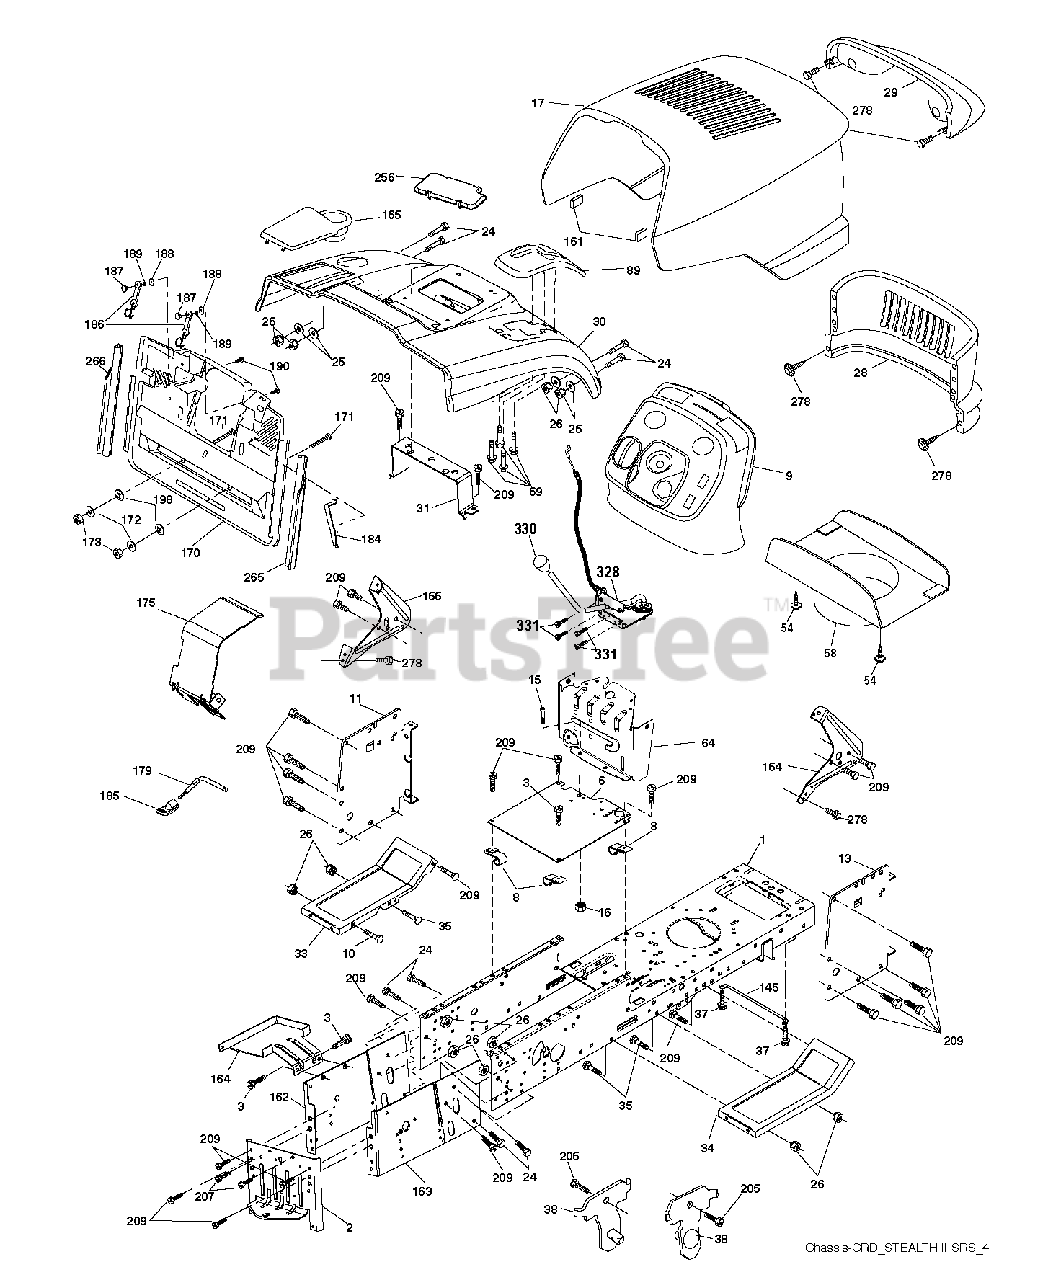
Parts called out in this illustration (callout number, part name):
1	CHASSIS
3	SCREW 3/8-16X3/4
8	CLIP,INSULATOR
10	BOLT D
13	PANEL DASH RH
16	NUT
25	WASHER
26	NUT
31	BRACKET SUPPORT FENDER
54	SCREW.WSHD.HEX10-32X5/8
58	DUCT HOOD
69	SCREW.HI-LO.CONSOLE
145	ROD.PIVOT.HOOD
161	EXTRUSION BUMPER
164	SUPPORT
171	BOLT
172	WASHER
186	LATCH ASSY
187	WELDNUT
189	LOCKWASHER
207	SCREW, 5/16-18 X 1/2
209	SCREW, 3/8-16X3/4
278	SCREW.#10 X 0.750.BOS THREAD
331	SCREW.#10-24X5/8.RN.QU
